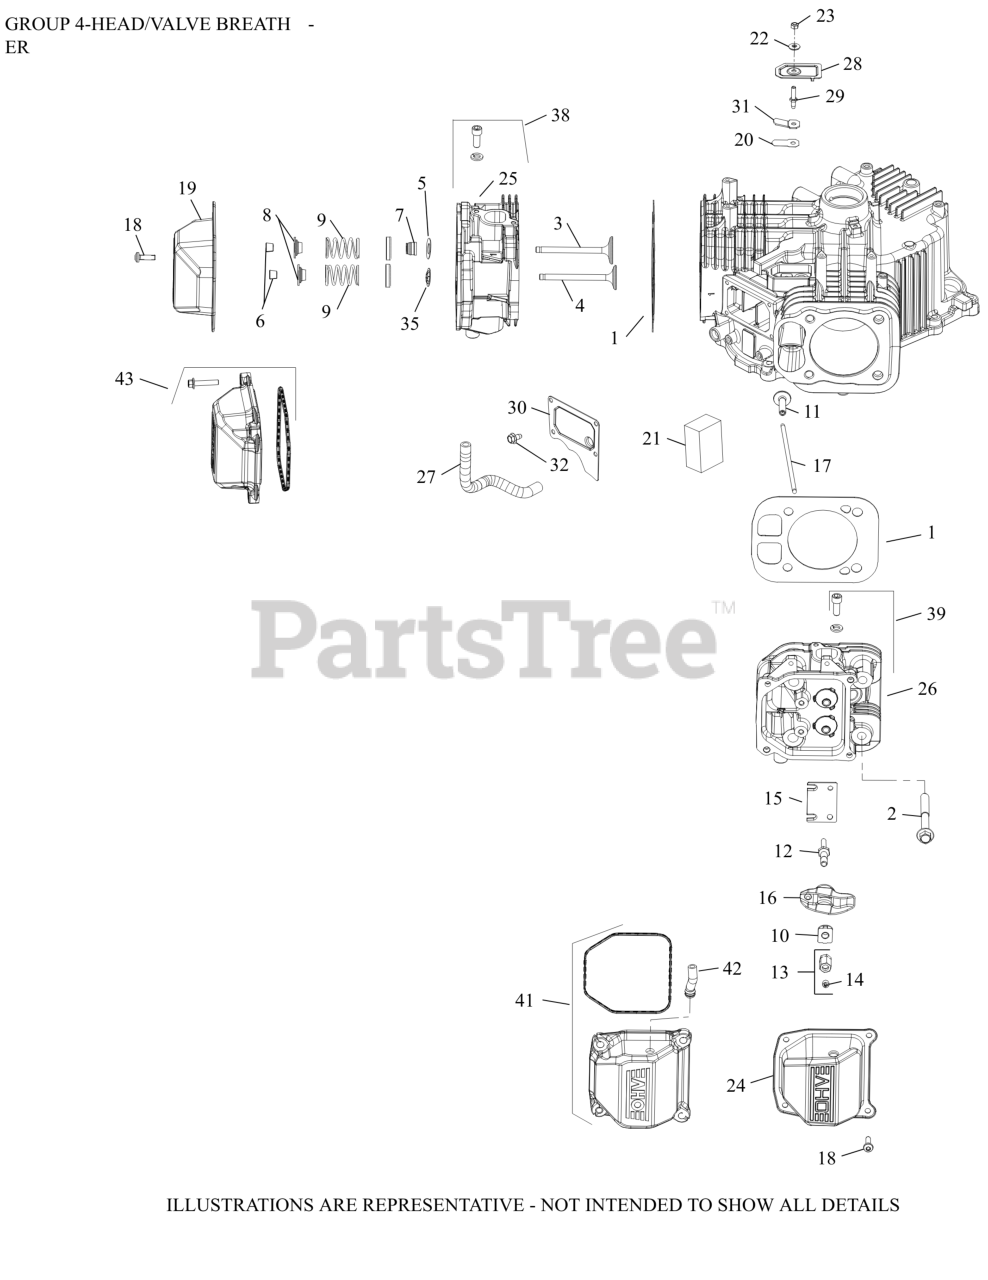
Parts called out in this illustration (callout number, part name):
1	KIT, CYLINDER HEAD GASKET
2	SCREW, FLG M10X1.5X90
3	VALVE, INTAKE
3	VALVE, INTAKE (.25) - (#2401702S)
4	VALVE, EXHAUST
4	VALVE, EXHAUST (.25)
5	SPACER (.010")
6	KIT, RETAINER
7	SEAL, VALVE BAND
8	CAP, VALVE SPRING
9	SPRING VALVE
10	PIVOT, ROCKER ARM
12	STUD, ROCKER
13	HEX NUT ASSEMBLY
14	SCREW, SET
15	PLATE, GUIDE
16	ARM, ROCKER
17	ROD, PUSH
18	SCREW, PAN HEAD
19	COVER, ROCKER STAMPED STEEL
20	REED, BREATHER
21	FILTER, BREATHER
22	WASHER, SEALING
23	NUT, LOCK M5X.8
24	COVER, ROCKER STAMPED STEEL
25	HEAD, ASSY CYL (#1)-USE 32 755 29-S
26	HEAD, ASSY CYL (#2)-(#3275530S)
27	HOSE, BREATHER
28	COVER, BREATHER REED
30	COVER, BREATHER MEDIA
31	RETAINER, REED
32	SCREW, THREAD FORMING
35	RETAINER, VALVE GUIDE (KM)
38	KIT, #1 HEAD AND HARDWARE-(#3275539S)
39	KIT, #2 HEAD AND HARDWARE-(#3275540S)
41	KIT,BREATHER VALVE COVER (PLASTIC)
42	KIT, FUEL PUMP HOSE(PLASTIC COVERS)
43	KIT, VALVE COVER-PLAIN (PLASTIC)
